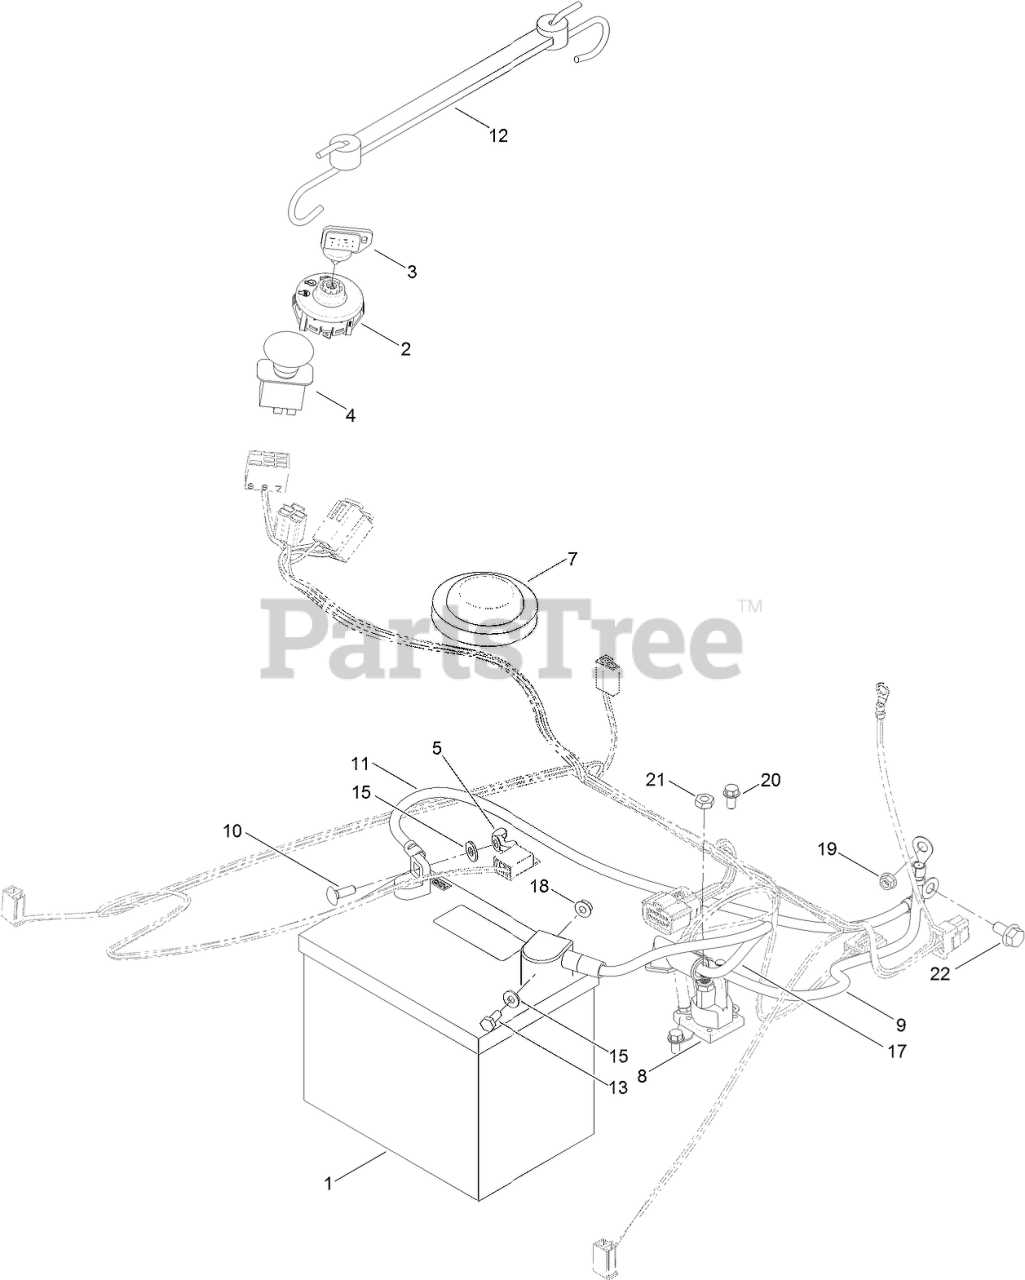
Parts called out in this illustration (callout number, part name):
1	BATTERY
2	SWITCH-IGNITION
3	KEY-IGNITION
4	SWITCH-PTO, ON-ON-(ON)
5	NUT-WING
7	SWITCH-SEAT
8	SOLENOID
9	CABLE-BATTERY, POSITIVE
10	BOLT-CARR
11	CABLE-BATTERY, BLACK
12	HOLDDOWN-BATTERY
13	SCREW-HH
15	WASHER-FLAT
17	CABLE-BATTERY, RED
18	NUT-HF
19	NUT-HF
20	SCREW-HWH
21	NUT-JAM
22	SCREW-HHF
